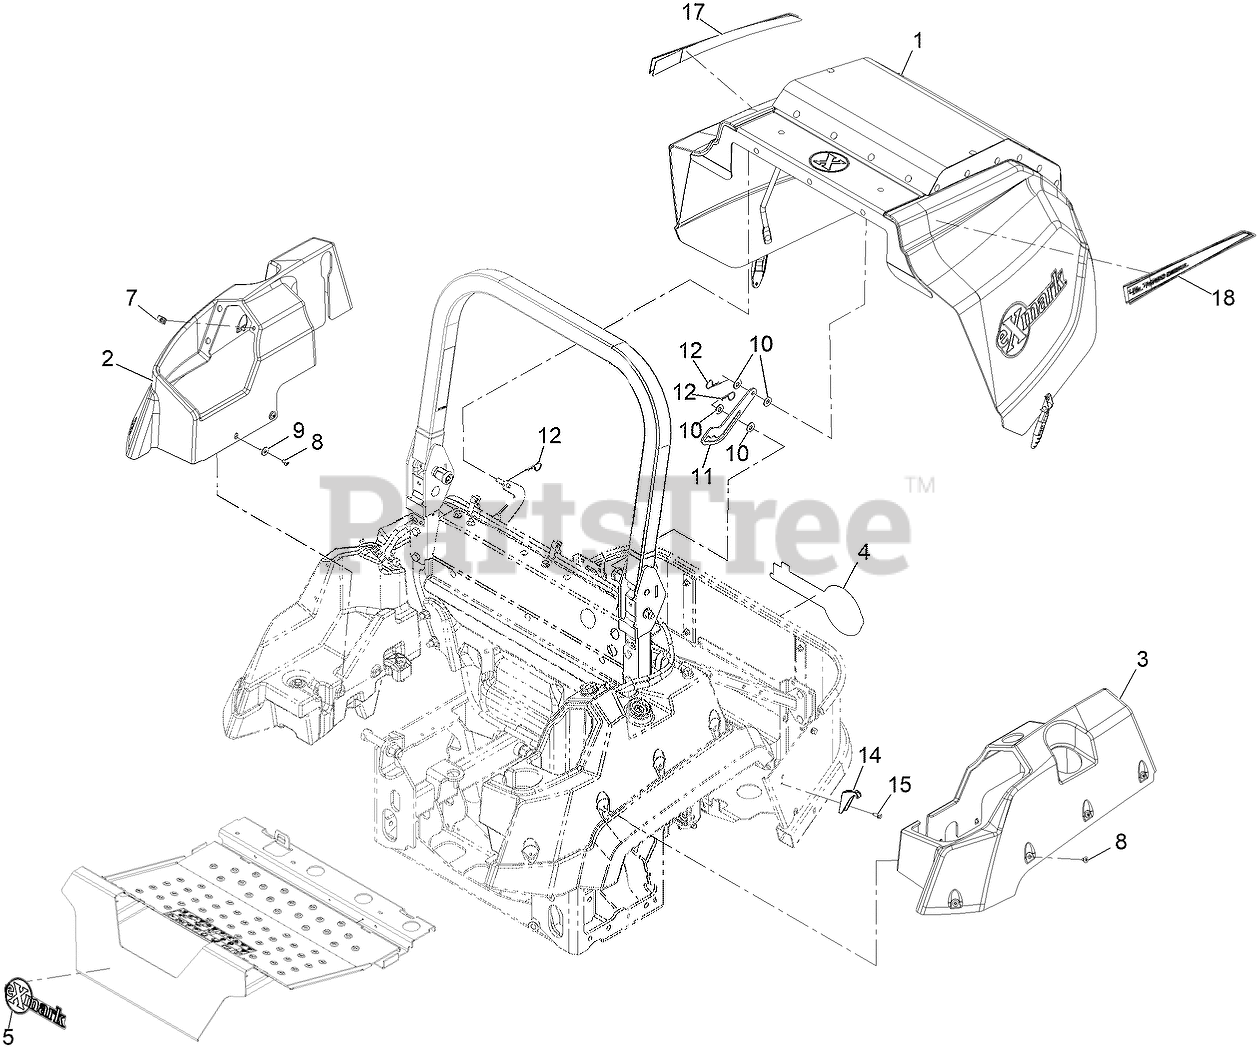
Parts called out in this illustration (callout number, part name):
1	ASM, HOOD LZSD
2	COVER-TANK, RH
3	COVER-TANK, LH
4	DECAL-EXMARK
5	DECAL-EXMARK
8	SCREW-TORX
9	WASHER-FLAT
10	WASHER-FLAT
11	PROP-HOOD
12	PIN-COTTER, HAIR
14	LATCH-CATCH
15	SCREW-HWH
17	DECAL-TURBO DIESEL-RH
18	DECAL-TURBO DIESEL-LH
